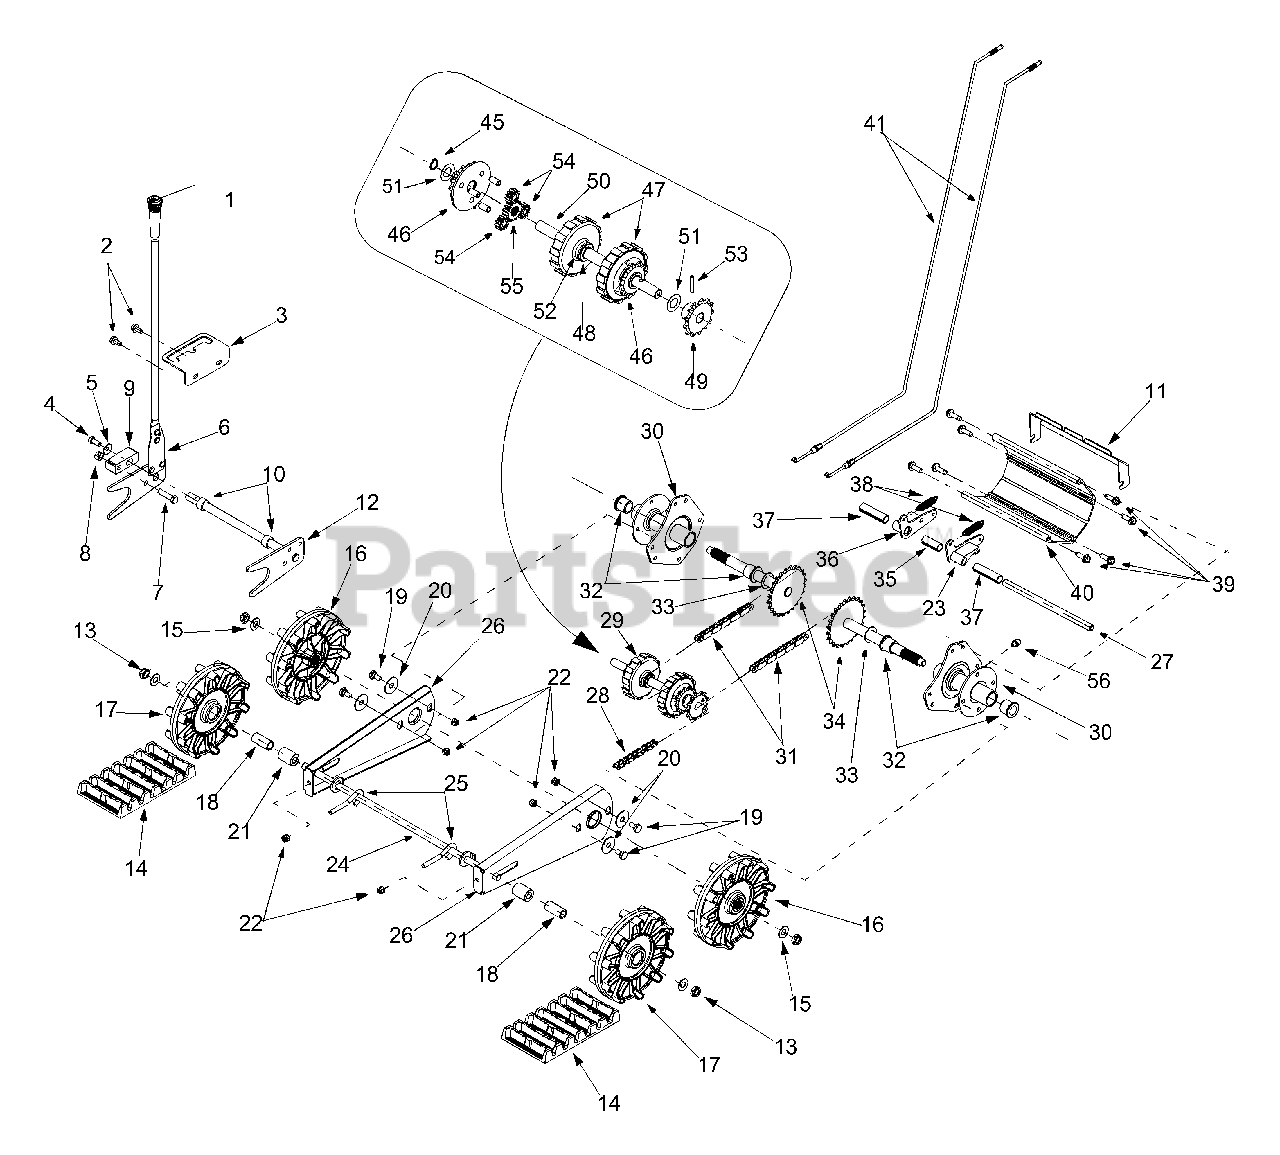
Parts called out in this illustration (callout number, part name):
2	Tap Screw, 5/16-18 x .625
4	Hex Cap Screw, 5/16-24 x .75
5	Bell Washer, .34 ID x .872 OD
7	Hex Cap Screw, 3/8-24 x 1.5
8	Hex Nut, 3/8-24
9	Lift Shaft Drive
10	Spacer, .628 ID x .875 OD x .5
13	Jam Nut, 1/2-20
14	Snow Track
15	Flat Washer, .5 x 1 x .06
16	Track Drive Wheel
17	Track Idler Wheel
18	Spacer, .51 ID x .75 OD x 1.67
19	Screw, .435 x .178-5/16 x .56
20	Flat Washer, .442 x 1.38 x .06
21	Spacer, .51 ID x 1 OD x 1.34
22	Hex Nut, 5/16-18
23	LH Dogg Assembly
25	Eye Bolt, 5/16-18 x 3
27	Actuator Shaft
28	Chain
29	Track/Steering Shaft Assy
31	Chain
32	Flange Bearing
33	Flat Washer, .793 x 1.24 x .06
34	Axle Assembly
35	Spacer, .514 x .630 x 1.59
36	RH Dogg Assembly
37	Spacer, .514 x .630 x 2.44
38	Extension Spring
39	Tap Screw, 5/16-18 x 1
40	Track Housing
41	Steering Cable
45	Retaining Ring
46	Carrier Assembly
47	Ring Gear
48	Retaining Ring
49	13-Tooth Sprocket
50	Track Steering Drive Shaft
51	Flat Washer, .58 x 1.06 x .02
52	Flat Washer, 5/8 x 1 x .03
53	Spiral Pin, 3/16 x 1
54	12-Tooth Gear
55	18-Tooth Gear
